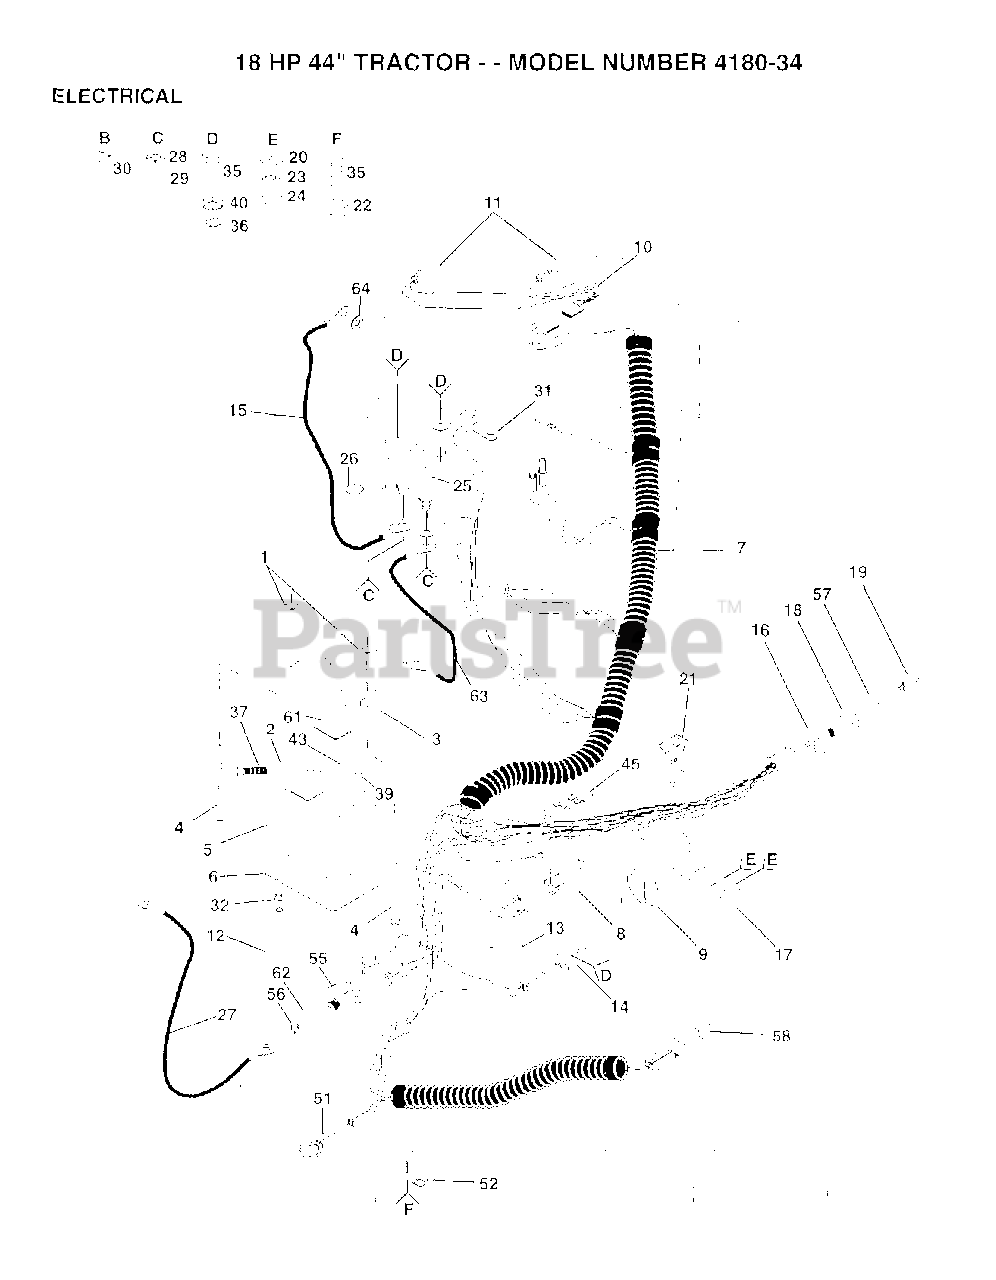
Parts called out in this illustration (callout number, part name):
1	WING NUT
2	WASHER
5	BATTERY
6	TRAY.BATTERY
7	Poulan TBD
8	RELAY.ASSY.T
9	AMMETER.ROUND.15 AMP
10	HARNESS, LIGHT SOCKET
12	BATT DRAIN TUBE T
13	WIRE TIE
14	SWITCH-INTER. GT
16	SWITCH YTV
17	AMMETER BRACKET
18	NUT
19	KEY.MOLDED.GENERIC
20	WASHER
21	SWITCH LT
22	NUT.CROWNLOCK.1/4
25	Solenoid Kit, .95
26	TERMINAL COVER
27	TIRE HEAVY DUTY
29	NUT
31	CLIP T
32	HOSE CLAMP T
35	BOLT
36	NUT
37	BOLT.HEX.1/4.X.3/4.DICHROMATE
39	NUT
40	LOCKWASHER
43	LOCKWASHER
45	FUSE *
51	LOOP-WIRE YTV
56	HEX NUT T (1 2)
57	COVER KEY IGNITIO
58	SWITCH SEAT
61	CAP BATTERY NLA
62	WASHER
63	BATTERY CABLE
64	LOCKWASHER
